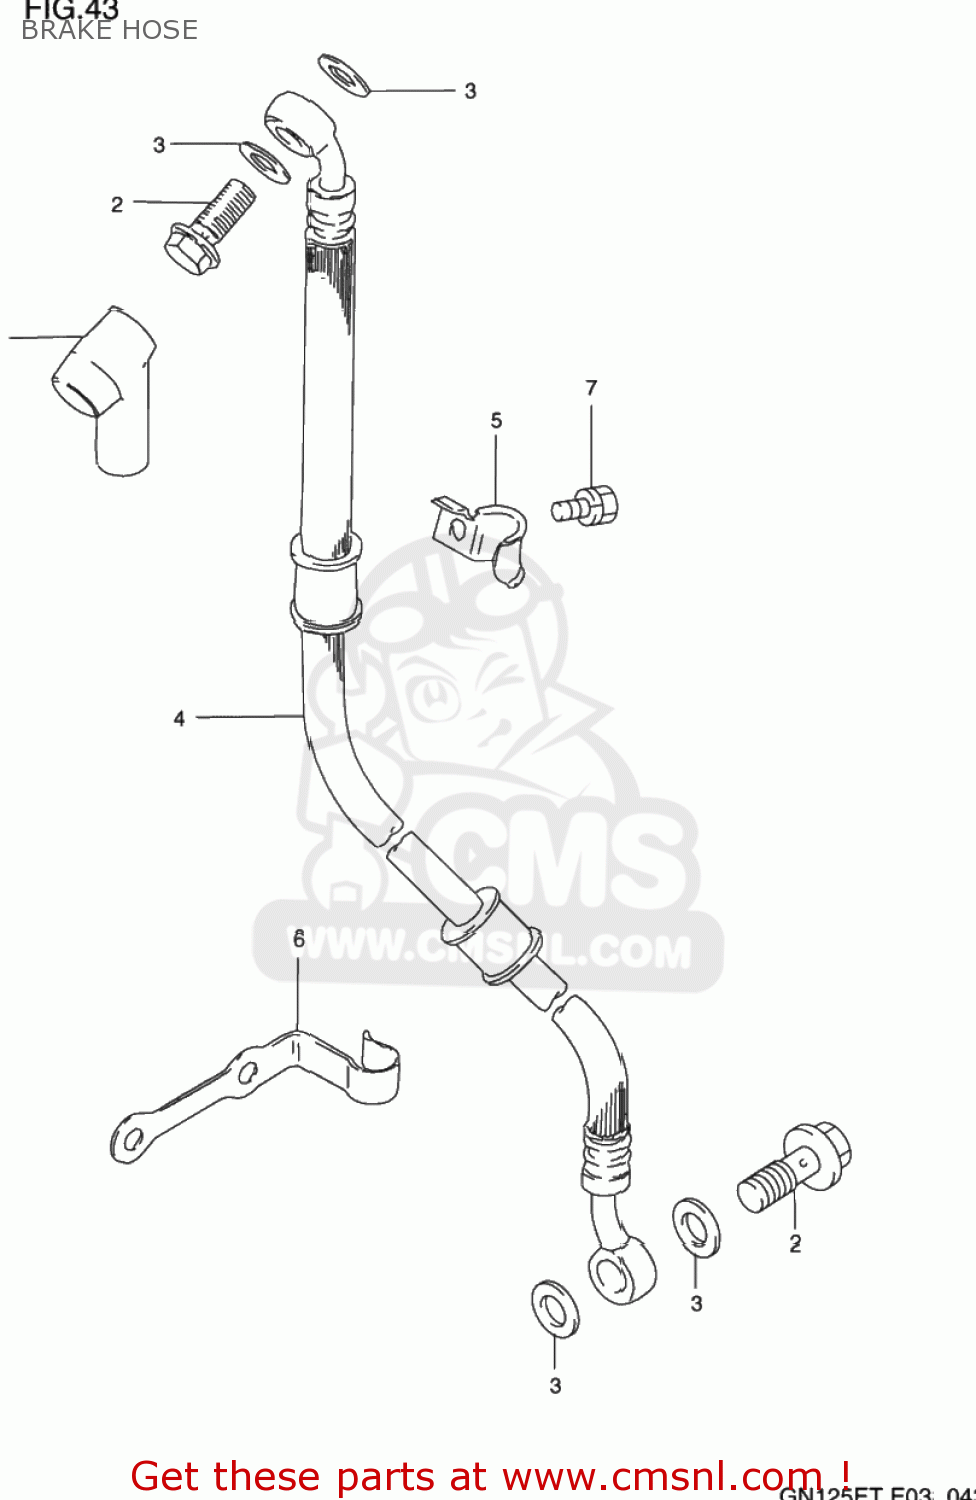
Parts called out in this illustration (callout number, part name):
1	BOOT,MASTER CYLINDER
2	BOLT UNION
3	WASHER(10X15X1.5)
4	HOSE,FR BRAKE
5	CLAMP,BRAKE HOSE
6	CLAMP,BRAKE HOSE
7	BOLT
